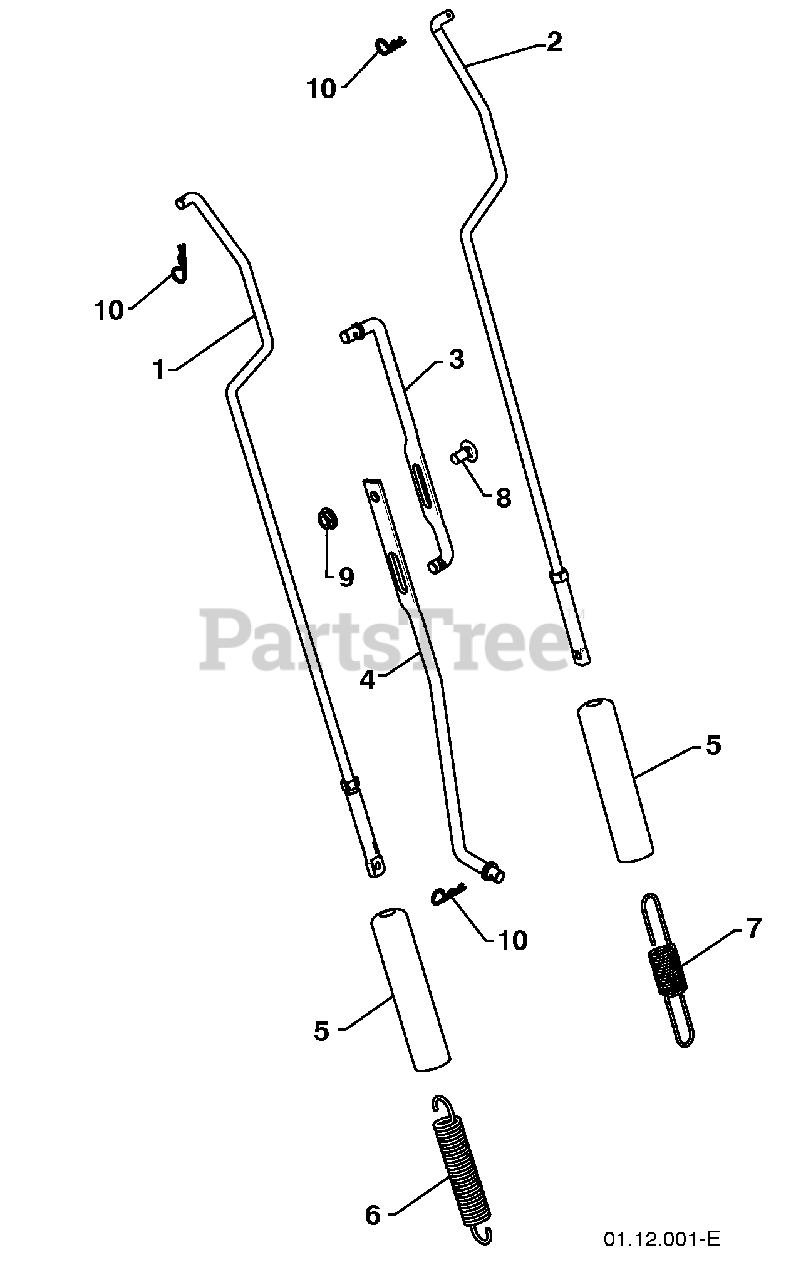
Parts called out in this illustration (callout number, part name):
1	IMPELLER ROD ASSEMBLY
2	TRACTION ROD ASSEMBLY
3	SHIFTER ROD TOP
4	SHIFTER ROD BOTTOM
5	SPRING SLEEVE
6	IMPELLER SPRING
7	TRACTION SPRING
8	CARRIAGE BOLT 5/16-18 X .75
9	NUT 5/16-18
10	RETAINER
